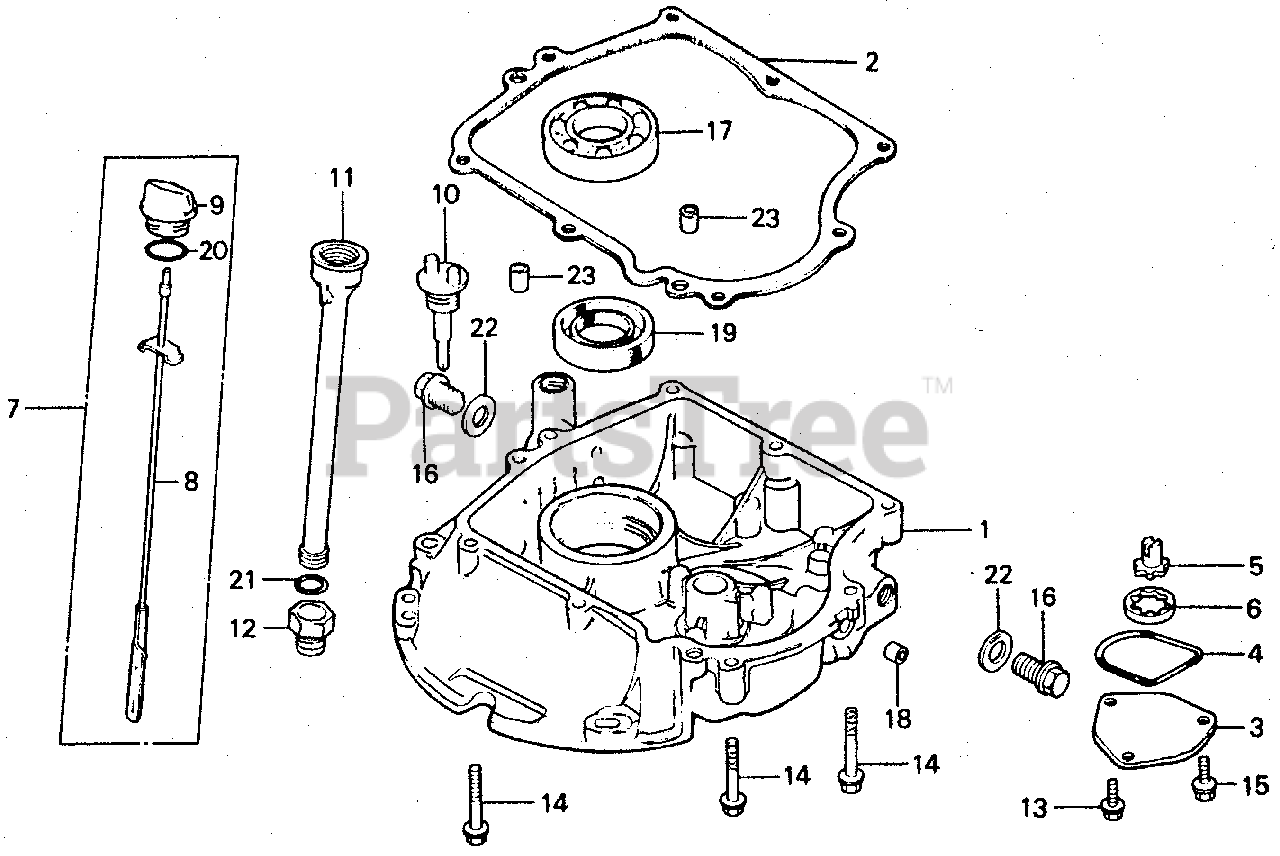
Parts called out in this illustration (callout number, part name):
2	GASKET, OIL PAN (NOT AVAILABLE)
3	COVER, OIL PUMP
4	O-RING, PUMP COVER (NOT AVAILABLE)
5	ROTOR (INNER) (NOT AVAILABLE)
6	ROTOR, OIL PUMP (OUTER)
7	GAUGE ASSY., LEVEL
7	GAUGE ASSY., OIL LEVEL
8	DIPSTICK, OIL
9	CAP, OIL (YELLOW)
10	CAP, OIL FILLER (NOT AVAILABLE)
11	PIPE, OIL FILLER
12	BOLT, JOINT (NOT AVAILABLE)
13	BOLT, FLANGE (6X12) (CT200)
14	BOLT, FLANGE (6X32) (CT200)
15	BOLT, FLANGE (6X16) (CT200)
16	BOLT, DRAIN PLUG (12X15)
17	BEARING, RADIAL BALL
18	OIL SEAL (6X11X4) (ARAI)
19	OIL SEAL (25.4X40X7)
20	O-RING (26X2.7)
21	O-RING (15X2.5)
22	WASHER, DRAIN PLUG (12MM)
23	PIN, DOWEL (8X14)
